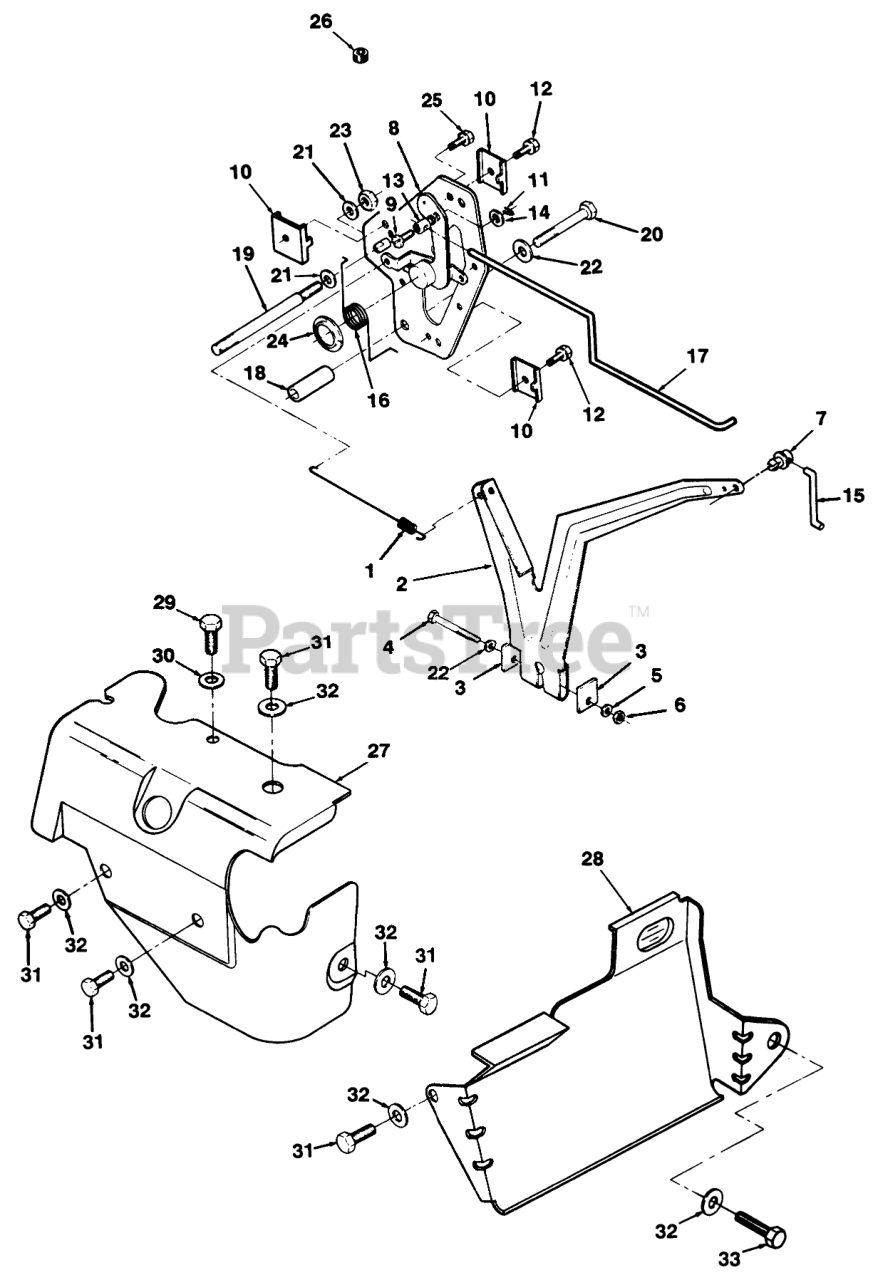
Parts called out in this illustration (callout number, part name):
1	SPRING-GOVERNOR
2	LEVER-GOVERNOR
3	WASHER
4	HHCS-M8 X 35MM
5	WASHER
6	Nut
7	Clip
8	PLATE-ASS'Y THROTTLE
9	HHMS #8-32X3/8"
10	Plug-Pipe
11	PIN-COTTER
12	SCREW-TAPPING
13	SWIVEL-CHOKE LEVER
14	Washer
15	LINK-THROTTLE
16	SPRING-CHOKE LINKAGE
17	LINK-CHOKE
18	SPACER
20	SCREW
21	WASHER-FLAT
22	WASHER-FLAT
23	NUT-HEX M6
24	Retaining Ring
25	STFHWH 12-24 X 1"
26	Plug
27	HSG-CYL AIR
28	Air Deflector
29	HHCS-M6 X 10MM
30	WASHER-FLAT
31	HHCS-M8 X 10MM
32	WASHER-FLAT
33	HHCS-M8 X 16MM
